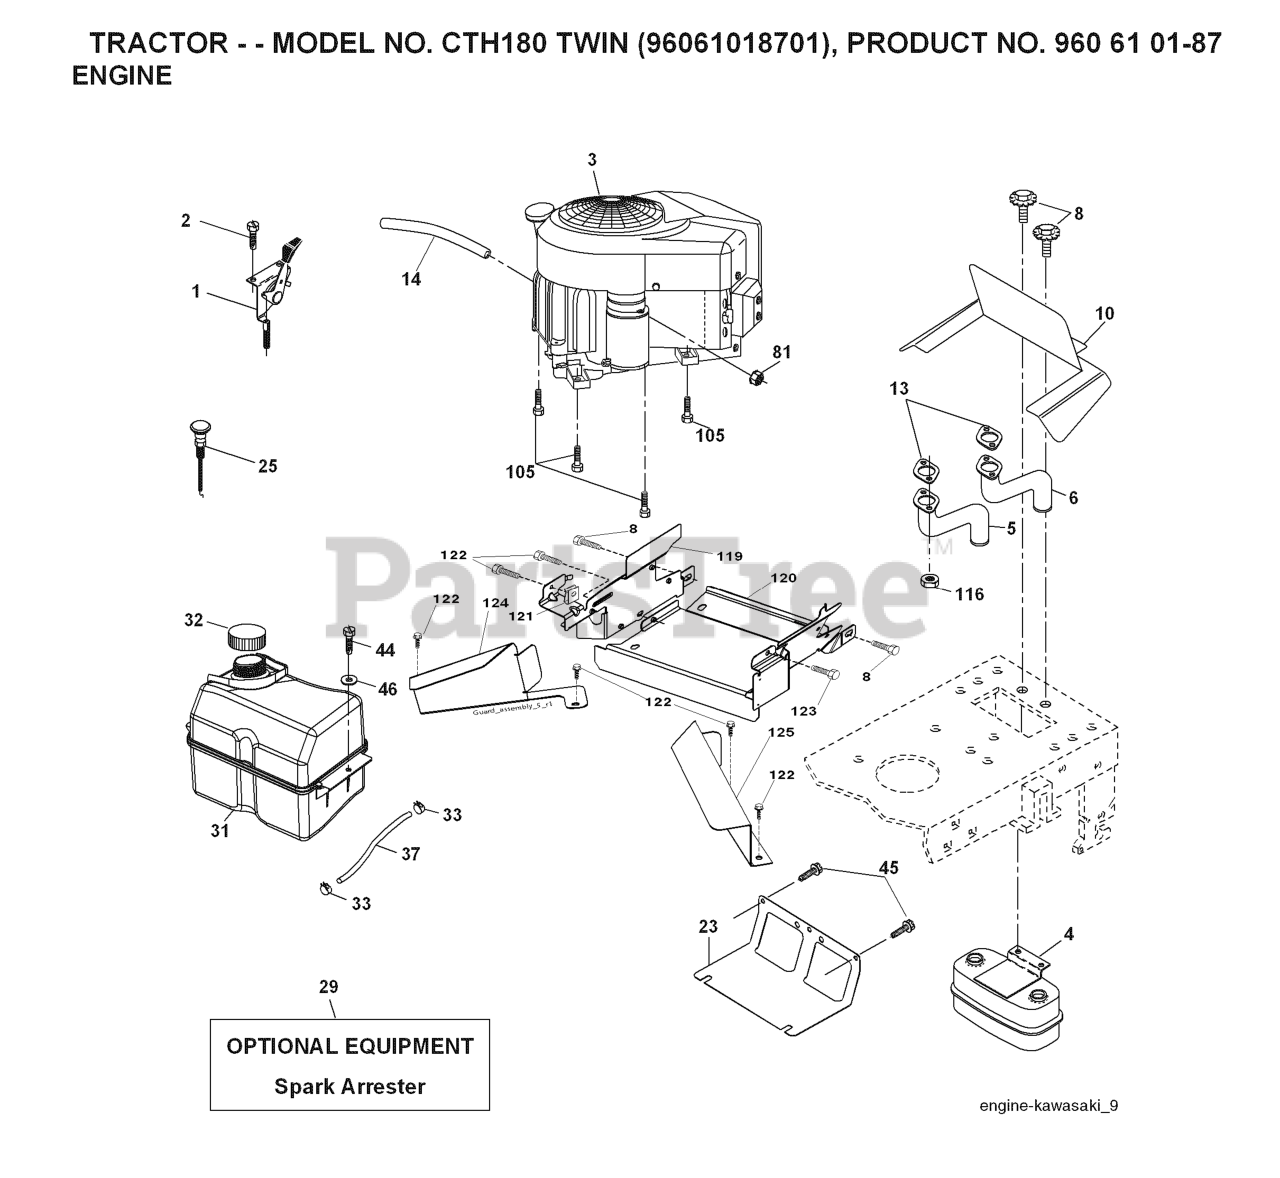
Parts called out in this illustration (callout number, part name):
1	THROTTLE CABLE
2	SCREW
4	MUFFLER.TWIN.CYL.LOW.TONE
5	EXHAUST.TUBE.RH.KAWASAKI.
6	EXHAUST.TUBE.LH.KAWASAKI.
8	BOLT.5/16-18UNCX3/4 W/SEMS.BLK
10	RP SHIELD HEAT MUFFLER
13	GASKET.EXHAUST.KAWASAKI.15-1
14	TUBE, DRAIN OIL ASM.
23	SHIELD.BROWNING.DBR.GUARD
25	CONTROL, CHOKE
29	KIT.SPARK ARRESTOR 794945 B&S
31	TANK.ASM.FUEL.FR.2.5GA.
32	FUEL CAP
33	HOSE CLAMP
37	LINE.FUEL.20
44	SCREW HEXWSHR 1/4-20X3/4
45	SCREW, 3/8-16X3/4
81	NUT
105	SCREW 3/8-16X1
116	NUT.HEX.FLANGE.TOPLOCK
119	LENKRAD
120	GUARD 532199767
122	SCREW.1/4-20X5/8
123	SCREW, 5/16-18 X 1/2
